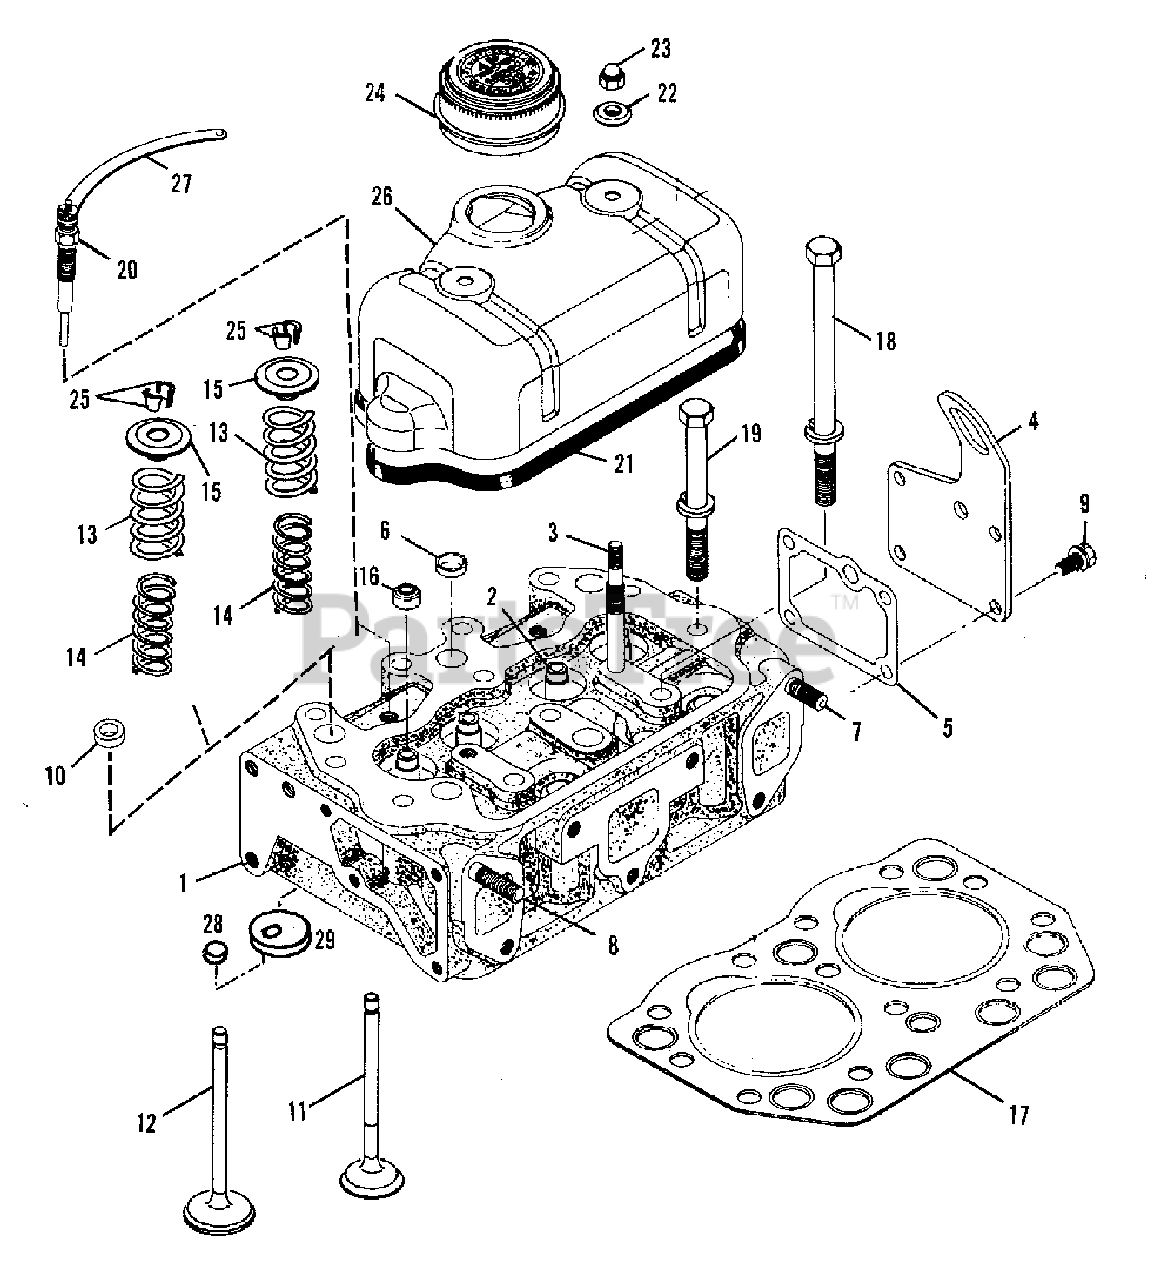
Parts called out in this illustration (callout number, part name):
1	HEAD ASSEMBLY, cyl. (Incl. Items 1 thru 10)
2	GUIDE, valve
3	STUD, M10 X 102 rocker bracket
4	COVER, water
7	STUD, M10 X 37
8	STUD, M10 x 49
9	CAPSCREW, M8 x 18, w/lockwasher, water cover
11	VALVE, intake
12	VALVE, exhaust
13	SPRING, valve, outer
14	SPRING, valve, inner
16	SEAL, valve stem
18	BOLT, M12 x 162 cylinder head, long
19	BOLT, M12 x 115 cylinder head
20	PLUG, glow
23	NUT, cylinder head cover
24	CAP, oil filler
25	LOCK, valve spring
26	COVER ASSEMBLY, cylinder head
27	PLATE, plug connecting
29	PIN, insert
